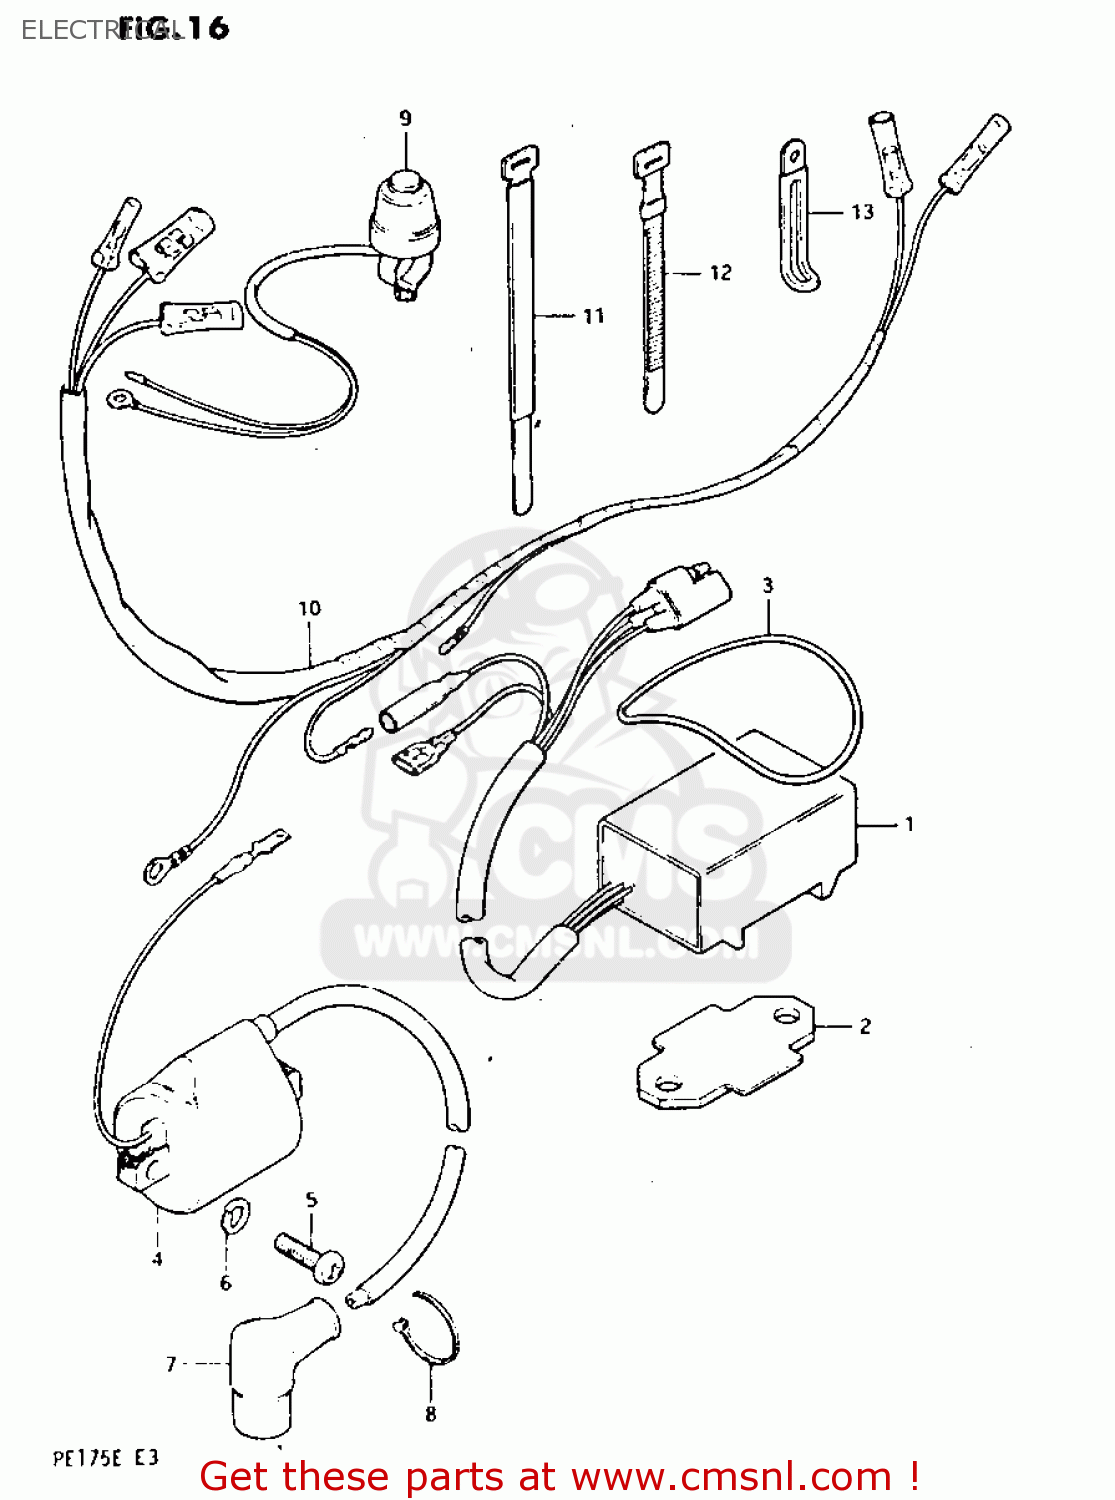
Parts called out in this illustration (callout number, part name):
1	CDI UNIT
2	PROTECTOR,CDI UNIT
3	O-RING
4	COIL ASSEMBLY,IGNITION
5	SCREW
6	WASHER,LOCK
7	CAP,SPARK PLUG
8	CLAMP
9	SWITCH ASSEMBLY
10	HARNESS,WIRING
11	CLAMP L:110
12	CLAMP(L:120)
13	CLAMP
